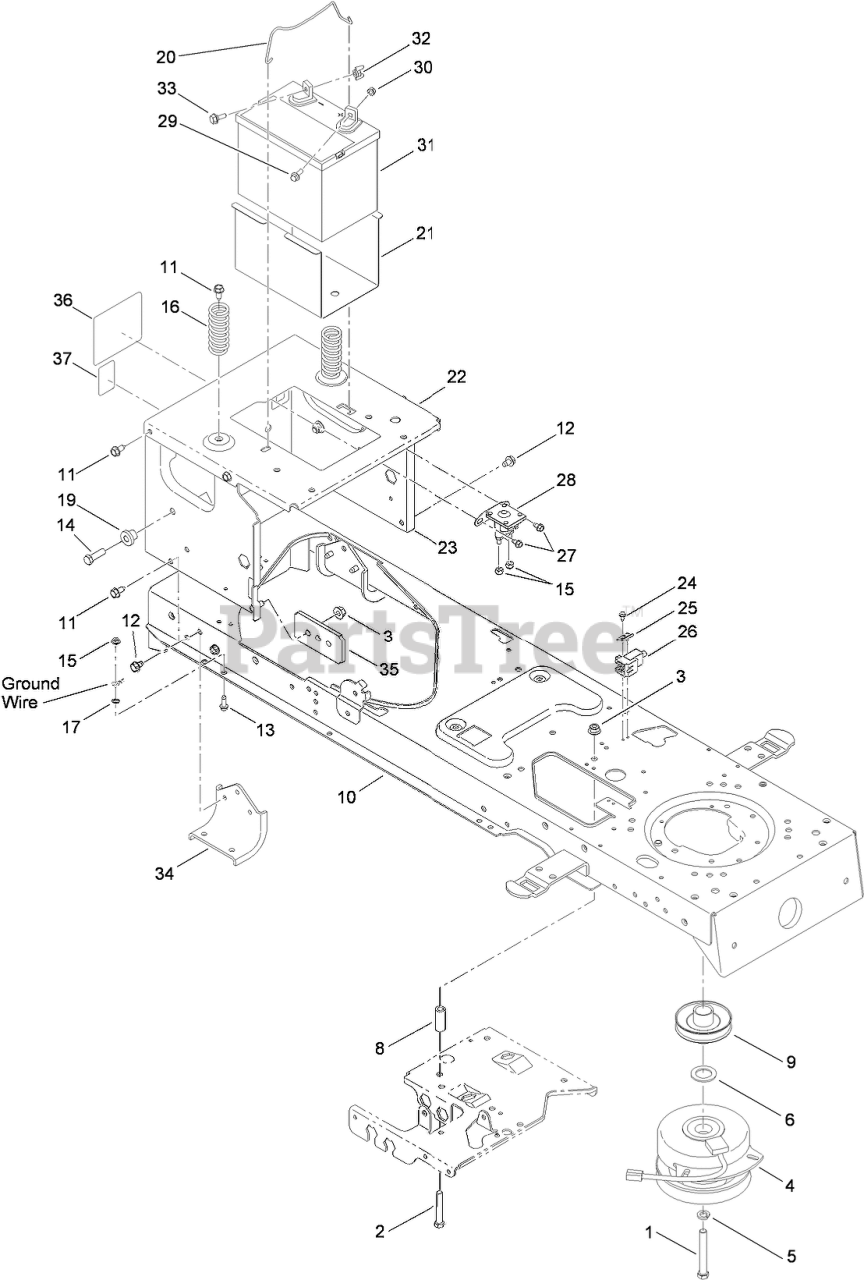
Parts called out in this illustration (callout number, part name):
1	SCREW-HH
2	SCREW-HH
3	NUT-LOCK, FLANGE
4	CLUTCH-ELECTRIC
5	WASHER-LOCK
6	WASHER-FLAT
8	SPACER
9	PULLEY-ENGINE
10	LOWER FRAME ASM
11	SCREW-TAP
12	SCREW-TAP
13	SCREW-TAP
14	SCREW-HH
15	NUT-LOCK, FLANGE
16	SPRING-COMPRESSION
17	WASHER-LOCK, EXTERNAL
19	SPACER-SHOULDER
20	ROD-HOLDDOWN, BATTERY
21	TRAY-BATTERY
22	BRACKET-FRAME, SEAT
23	FRAME-UPPER
24	SCREW-TAP
25	PLATE-SWITCH
26	SWITCH-INTERLOCK
27	SCREW-HWHTF
28	SOLENOID-12V, 2 POST 2 Tab
29	BOLT-CARRIAGE
30	NUT-SEMS
31	BATTERY-245, CCA (DRY FLAT TOP)
32	NUT-WING
33	BOLT-SHOULDER
34	BRACKET-AXLE
35	PLATE-SUPPORT
36	DECAL-TORO
37	DECAL-HYDRO RELEASE
